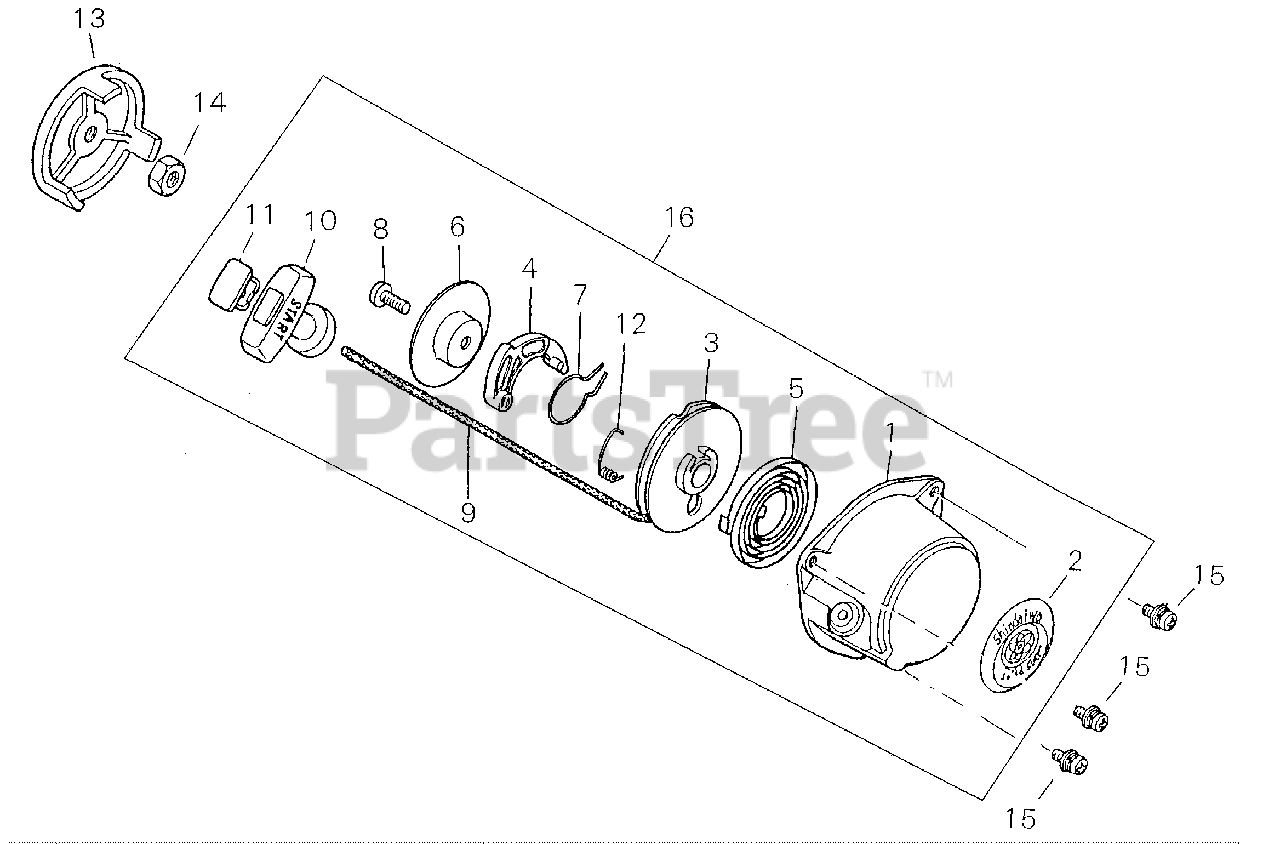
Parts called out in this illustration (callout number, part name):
1	CASE, STARTER
2	NAME PLATE
3	REEL, ROPE
4	PAWL, STARTER
5	SPRING, REWIND
6	PLATE, STARTER
7	SPRING
8	SCREW
9	ROPE
10	GRIP, STARTER
11	RETAINER, ROPE
12	SPRING, RETURN
13	CATCHER, STARTER
14	NUT - 8
15	SCREW - 5X16
16	STARTER ASSY
